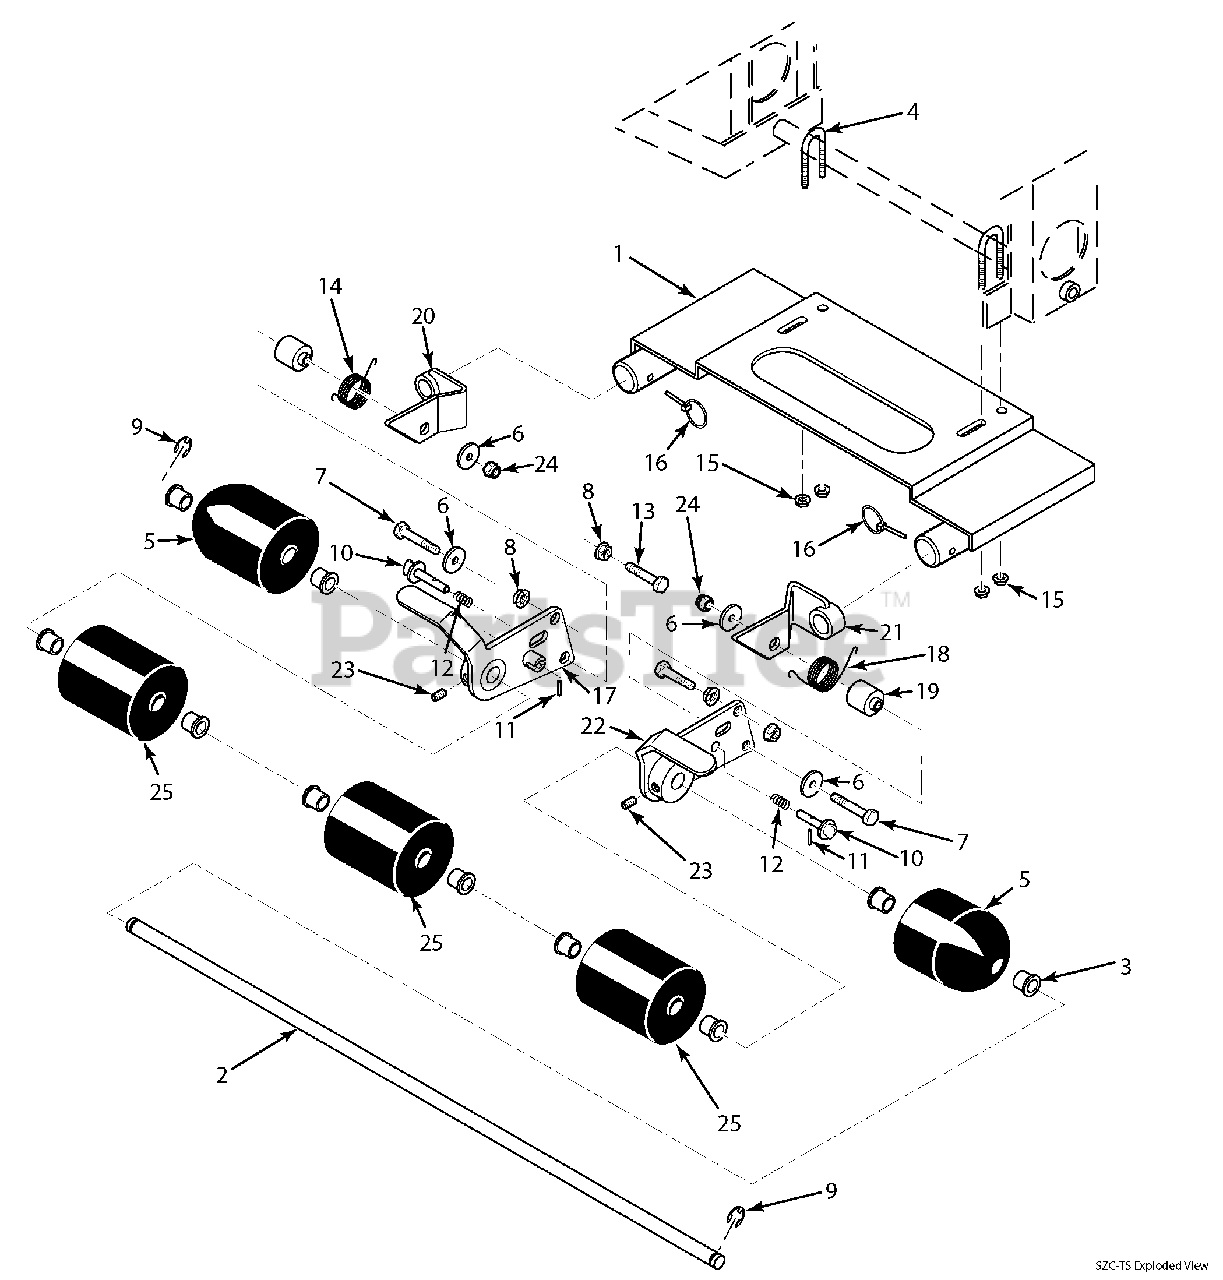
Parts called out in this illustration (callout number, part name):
1	Striper Mounting Bracket
2	Roller Shaft
3	Bushing, .752 Oilite
4	U-Bolt, 5/16-18 x 1"
5	Roller Assembly, Striper End
6	Flatwasher, 3/8-.406 x 1-1/2" 7 Gauge
7	Bolt, Hex Head 3/8-16 x 2-3/4"
8	Nut, Serrated Flange 3/8-16
9	Retaining Ring, .750 External "E"
10	Pin, Lift Latch
11	Pin, Slotted Spring .156 x 3/4"
12	Spring, Lock Pin
13	Bolt, Hex Head 3/8-16 x 2-1/2"
14	Spring, Torsion L.H.
15	Nut, Serrated Flange 5/16-18
16	Quick Pin, .188 Dia.
17	Hinge Weldment, L.H.
18	Spring, Torsion R.H.
19	Hub, Striper
20	Pivot Weldment, L.H.
21	Pivot Weldment, R.H.
22	Hinge Weldment, R.H.
23	Set Screw, 3/8-16 x 1/2"
24	Nut, Elastic Stop 3/8-16
25	Roller Assembly
